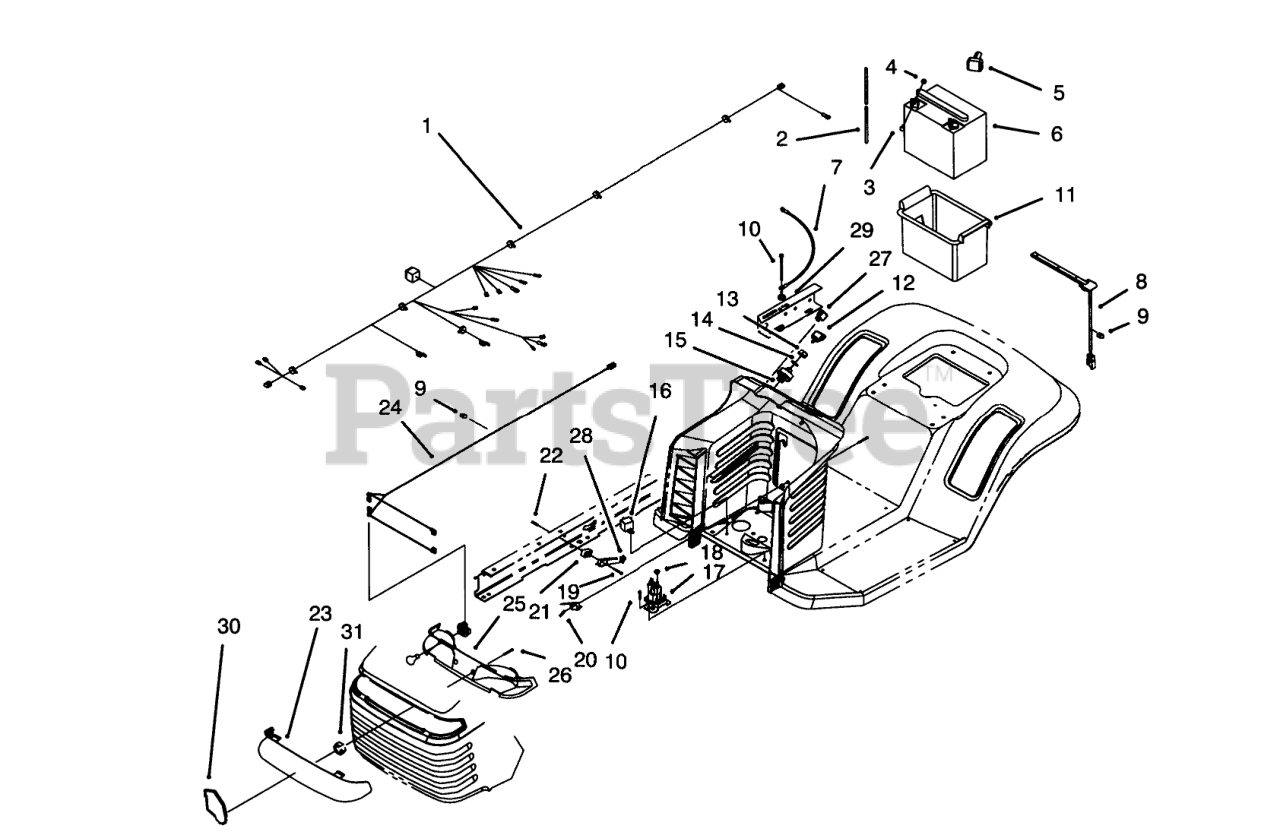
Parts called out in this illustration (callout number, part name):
1	WIRE HARNESS
2	TUBE-BATT DRAIN/80-2600
3	SCREW-HH
4	NUT-WING
5	BOOT-TERMINAL
6	Battery
7	WIRE ASM
8	SWITCH-SEAT
9	CLIP-RETAINER, WIRE
10	SCREW-HWH
11	BOX-BATTERY
12	KEY-IGNITION
13	NUT-HH
14	WASHER-TOOTH, INTERNAL
15	Key Switch ASM
16	RELAY
17	Solenoid
18	NUT-KEPS
19	SCREW-HH
20	SWITCH-MICRO
21	SPACER
22	NUT-SPEED
23	LENS-HEADLIGHT
24	HARNESS-WIRE, LIGHTS
25	HEADLIGHT REFLECTOR ASM
27	SWITCH-ROCKER
28	PLUNGER-SEAL
29	WASHER-LOCK/EXT
30	EMBLEM-GRILLE WHEELHORSE
